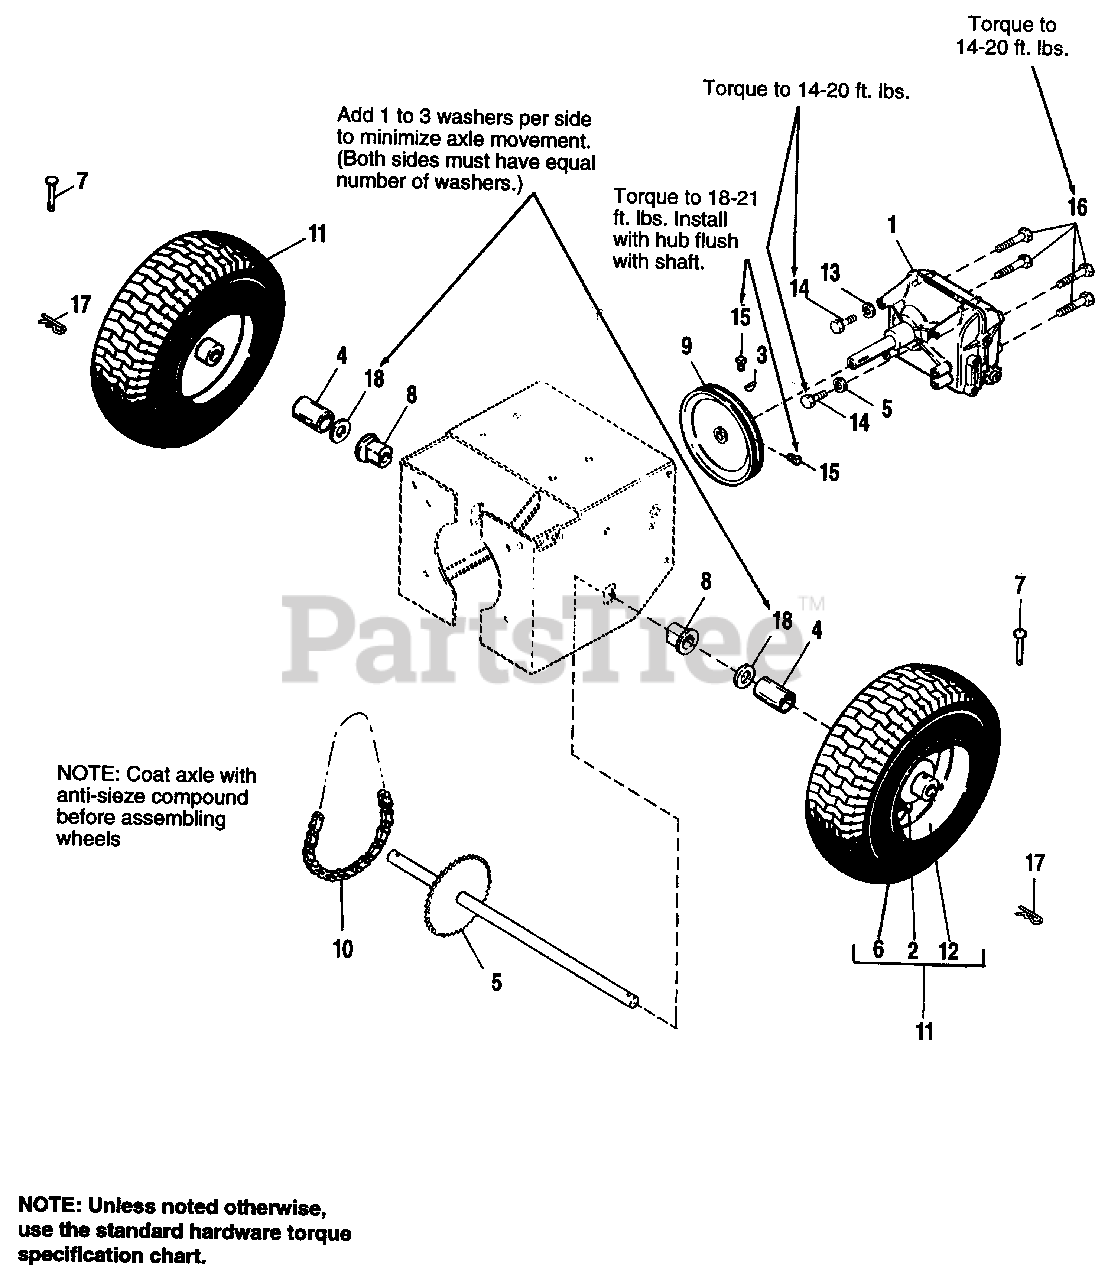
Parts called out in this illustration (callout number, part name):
2	VALVE STEM & CAP
3	KEY, Woodruff, Hi Pro, 3/16 x 3/4
4	SPACER, Wheel
5	AXLE & SPROCKET ASSY.
6	TIRE, Snow Hog Tread, 4.10-6
7	PIN, Clevis
8	BUSHING, Wheel
9	PULLEY ASSY., Traction
10	DRIVE CHAIN
11	TIRE & WHEEL ASSY., (Incl. Ref. Nos. 2, 6 & 12)
12	WHEEL, (Metallic Grey)
13	LOCKWASHER
14	CAPSCREW, Hex, 5/16-18 x 3/4
15	SETSCREW, Sq. Hd., 5/16-18 x 5/8
16	SCREW, Hex, Taptite, 5/16-18 x 5/8
17	CLIP, Hair Pin
18	WASHER
